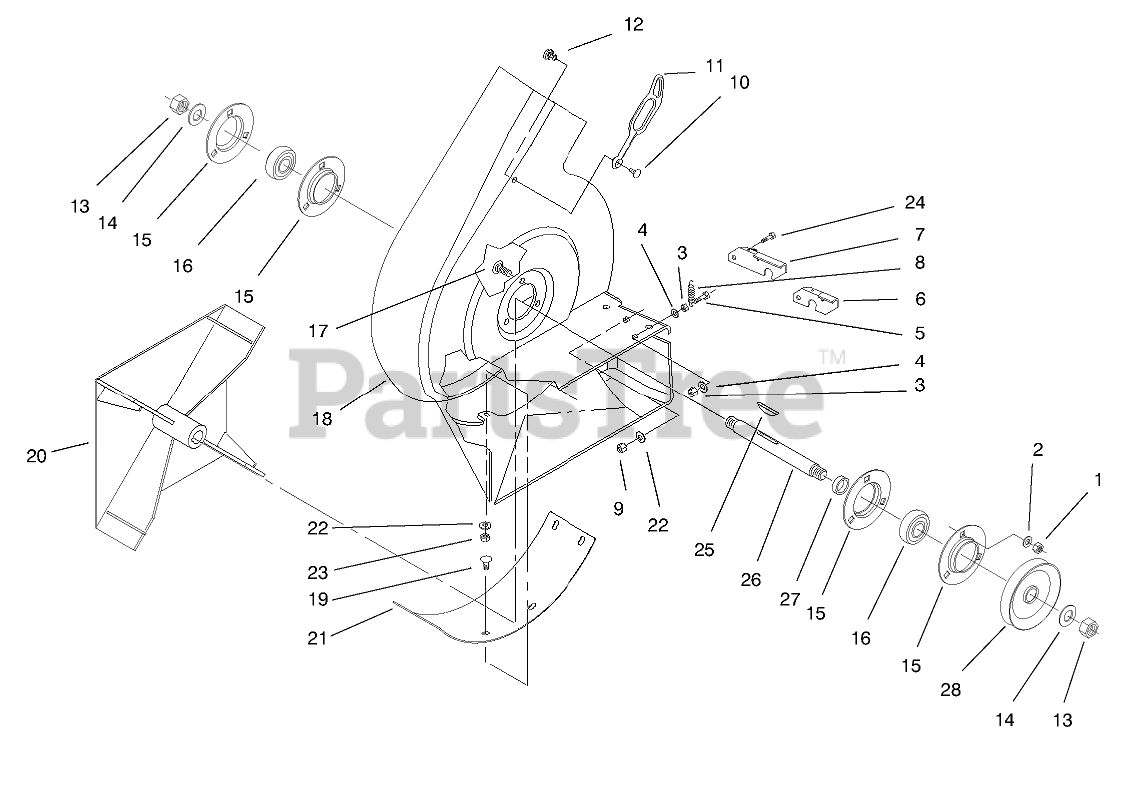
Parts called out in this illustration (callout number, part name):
1	NUT-HEX
2	WASHER-LOCK
3	NUT-HEX
4	WASHER-FLAT
5	SCREW-HWH
6	42" BLOWER LATCH B
7	48" BLOWER LATCH B
8	SPRING-EXTENSION
9	NUT-LOCK, NI
10	FASTENER-PANEL
11	RETAINER-DUCT
12	SPACER-INTERLOCK
13	NUT-JAM
14	WASHER-LOCK
15	FLANGE
16	BEARING-BALL
17	SCREW-CARR
18	HOUSING-VAC, BLOWER
19	SCREW-CARRIAGE
20	Impeller
21	COVER-BLOWER, BOTTOM
22	WASHER-FLAT
23	NUT-LOCK, NI
24	SCREW-HH
26	SHAFT-BLOWER
27	Spacer
28	PULLEY-BLOWER
